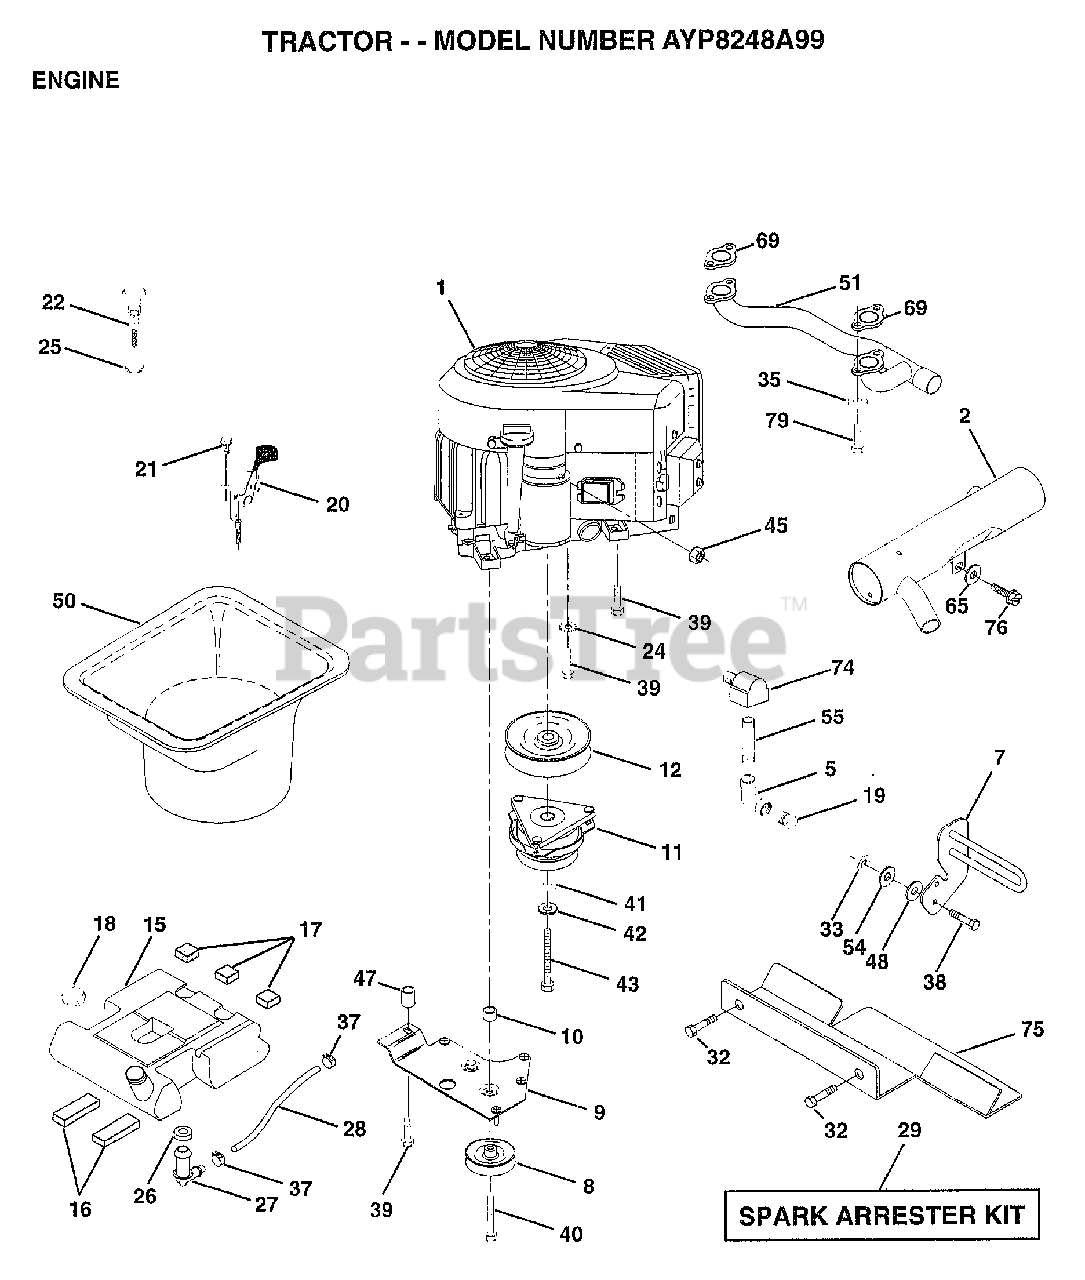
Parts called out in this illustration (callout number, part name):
2	MUFFLER.SIDE.VGT
5	ELBOW
7	GUARD.MUFFLER.ASM
9	KEEPER ASM BELT
10	BUSHING.
12	PULLEY.ENG.CLUTCH
15	TANK FUEL REAR
16	PAD IDLER TI
17	PAD-SPACER LT
18	CAP ASM FUEL
19	PLUG T
20	CONTROL.TRTL.37
21	SCREW LT
22	CHOKE CONTROL
24	LOCKWASHER
25	"NUT,KEPS 3/8-24IM"
26	BUSHING OUTLET T
27	STEM.TANK.FUEL
29	SPARK ARREST KIT
32	SCREW LT
33	NUT
35	LOCKWASHER
37	HOSE CLAMP
38	"BOLT,HEX"
39	SCREW.3/8-16X2.25
40	SCREW.TT.3/8-16X4
41	WASHER
42	LOCKWASHER
43	BOLT.7/16-20X4.25
45	NUT
47	SPACER.ENGINE
48	WASHER T
50	DUCT AIR VGT INTEK
51	MANIFOLD.PIPE.VGT
54	WASHER
55	PIPE NIPPLE LT
65	WASHER
74	ELBOW STREET BASS
75	SHIELD.HEAT.INTEK.VGT
76	SCREW
79	SCREW
